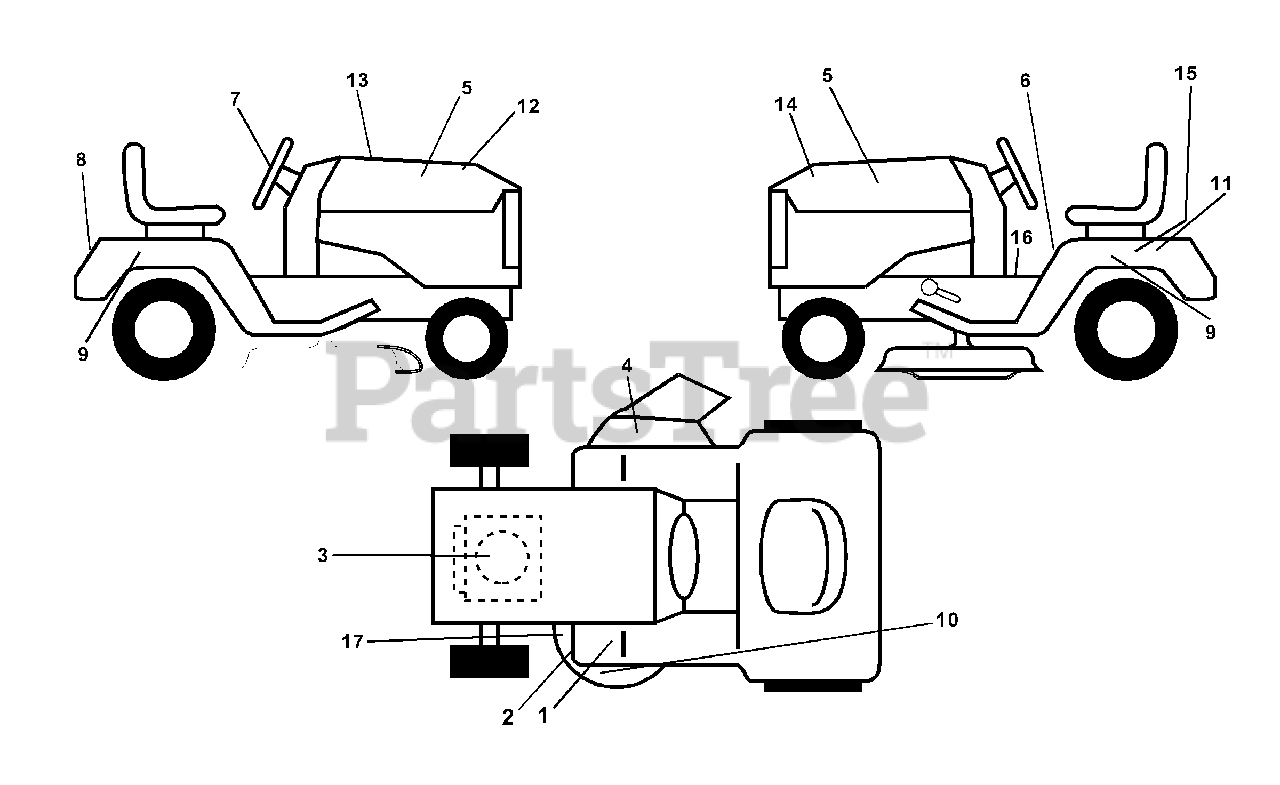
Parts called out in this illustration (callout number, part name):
1	Decal, Clutch/Brake Eng
2	Decal V-Belt Schematic
3	Decal, Engine HP
4	Decal Warning
5	Decal, Pnl Sd
6	Decal, Fender Danger English
7	Decal Ins Str Wh
8	Decal, Logo, Fender
9	Decal Fender
10	Decal, Deck Enviro
11	Decal, Battery
12	Decal, Hood RH
13	Decal, Replacement
14	Decal, Hood LH
15	Decal, Caution, Battery
16	Decal, Oper Sdl P/L Gear Dr Eng
17	Decal, V-Belt Sch.
